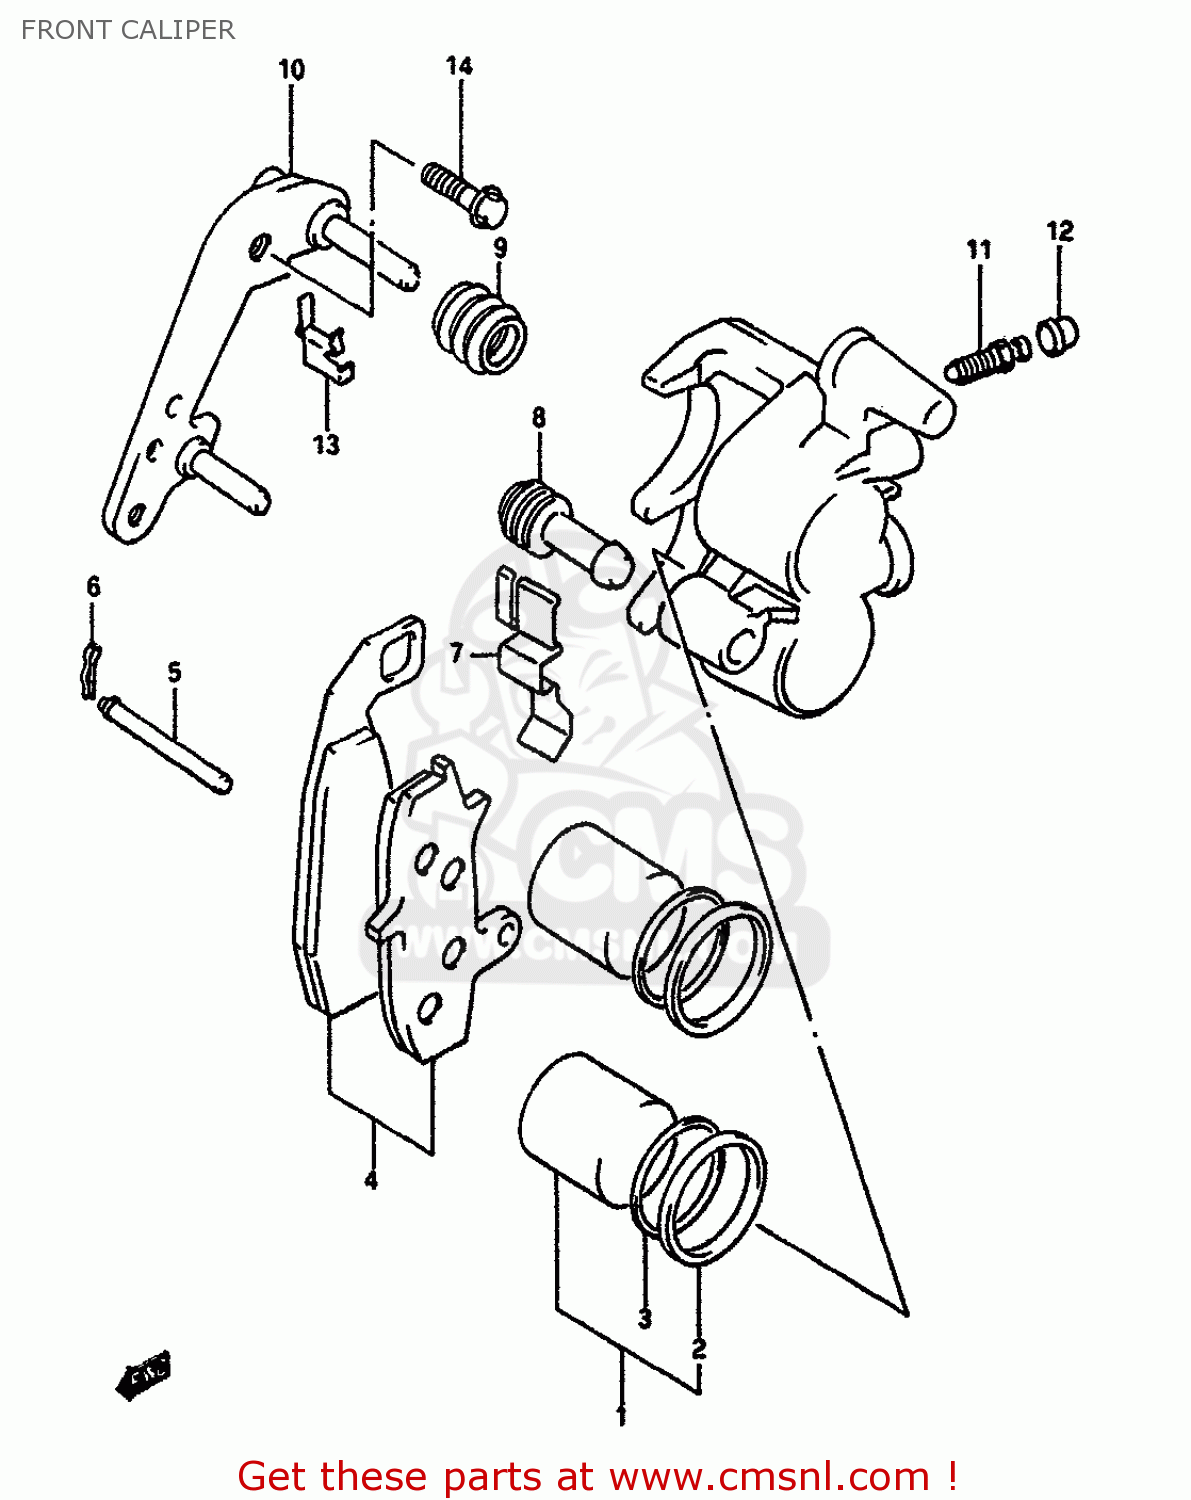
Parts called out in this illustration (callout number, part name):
1	PISTON SET
2	SEAL,PISTON
3	SEAL,WIPER
4	PAD SET (NAS)
5	PIN,PAD
6	CLIP,PAD PIN
7	SPRING,PAD
8	INSULATOR,AXLE
9	BOOT,AXLE
10	BRACKET
11	BLEEDER
12	CAP,BREATHER
13	GUIDE,PAD
14	BOLT
